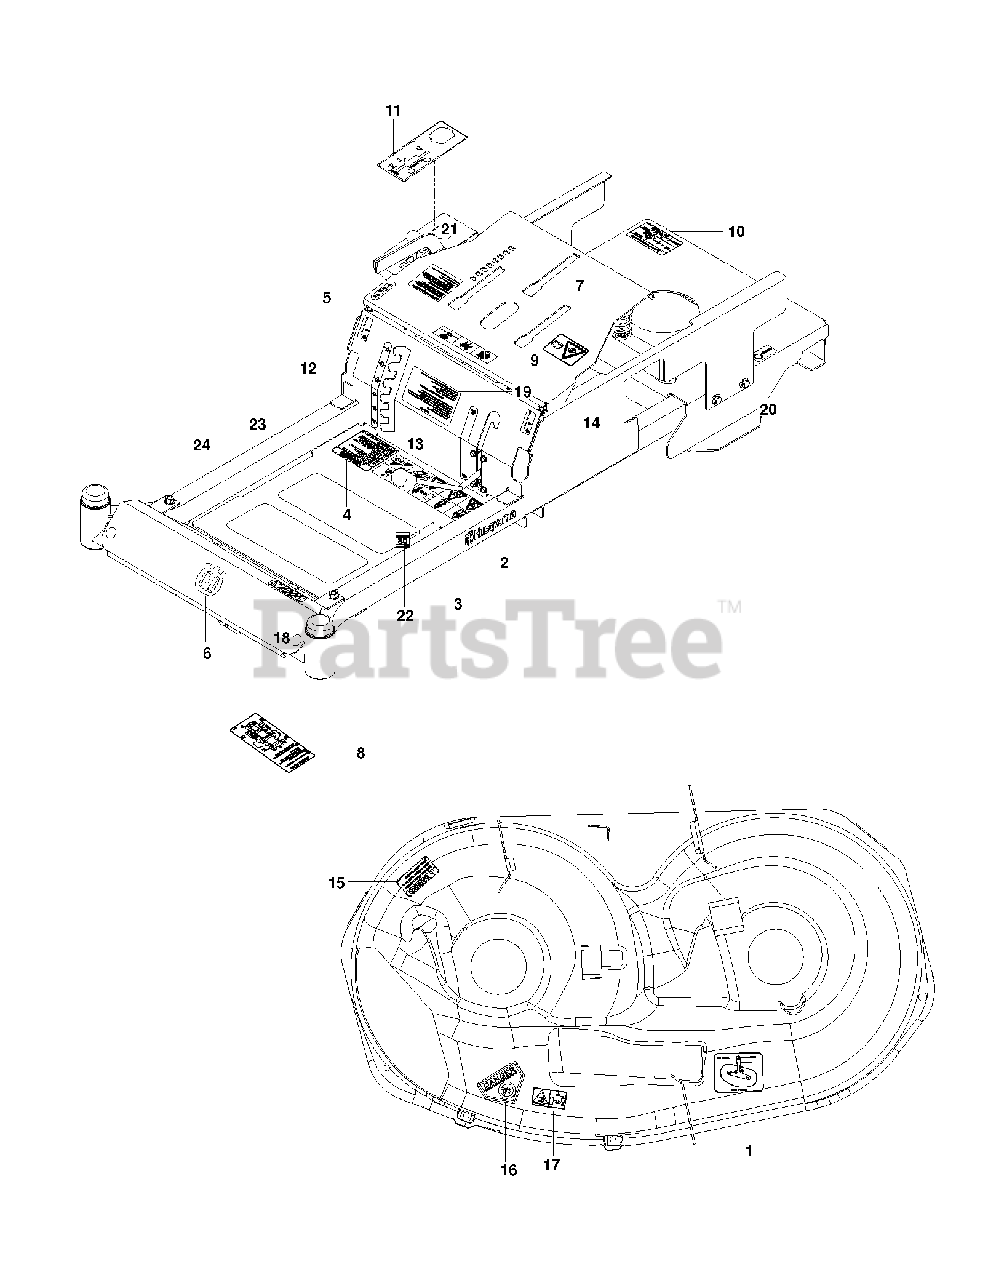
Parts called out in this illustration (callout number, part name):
1	DECAL, BELT ROUTING
2	RP.DECAL.BADGE.170MM.TEXTLOGO
3	DECAL, SAFETY WARNING
4	DECAL, WARNING
5	DECAL, PARK BRAKE
6	DECAL.AUGER.HUSQ.CROWN.SNOW
7	DECAL, EXITING MOWER
8	DECAL, SERVICE
9	EURO DECAL-BATTERY WARNIN6
10	DECAL, DO NOT TOW
11	DECAL, CONTROL PANEL HUS
12	DECAL, DECK HEIGHT
13	DECAL, BLADE ENGAGEMENT
14	DECAL, MOTION CONTROL
15	DECAL, CAUTION
16	DECAL, CPSC
17	DECAL, EURO SEVERING
18	DECAL RZ4221
19	DECAL, START
20	DECAL, ECM, AUSTRALIA
21	DECAL, CUSTOMER RESPNSIBILITY
22	DECAL 80 DBA
23	ANTI-SKID PAD
